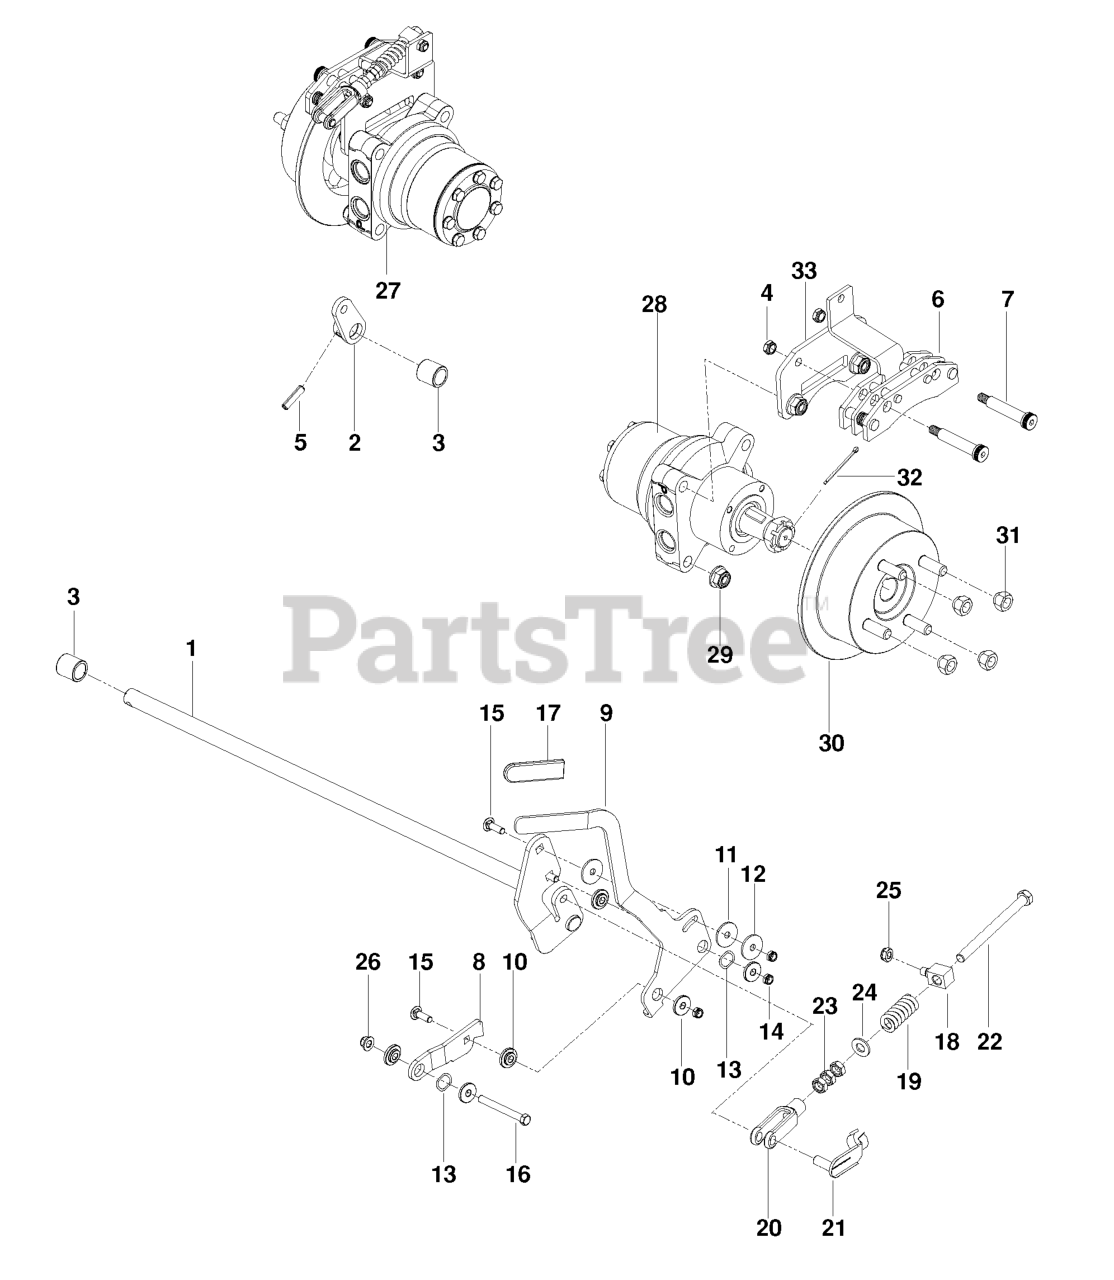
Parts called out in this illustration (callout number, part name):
1	SHAFT, BRAKE WLDMT
2	ARM, RT BRAKE
3	BUSHING, SLEEVE 3/4 X 1.0
4	NUT HEX 3/8-16 NYLON, THIN
5	5/16 DIA ROLL PIN
7	BOLT, SHOULDER, 1/2 X 2.25
8	LINK, FOLLOWER
9	LEVER.BRAKE.BLACK
10	BUSHING, BRAKE
11	WASHER, FRICTION, 1/8
12	CONE WASHER
13	WASHER, .825 X 1.087, WAVE
14	NUT HEX 3/8-16 NYLON, THIN
15	RHSNB 3/8-16 X 1-1/4
16	HCS 3/8-16 X 3-1/4 GR5 ZD
18	SWIVEL, BRAKE
20	YOKE-3/8-24 PLTD
21	PIN, CLEVIS SPRING, 3/8
22	HCS 3/8F X SPECIAL
23	NUT 3/8-24 JAM
24	WASHER 3/8 SAE FLAT
25	5/16-18 THIN PROF NY
26	NUT 3/8-16 HEX FLG NYLOC ZD
27	MOTOR, TL0310, RT
28	MOTOR, TL0310, LT
29	NUT, 1/2-13 HEX FLG NYLOC ZD
30	HUB, DISC BRAKE, W/STUDS
31	LUG NUT 1/2F
32	COTTER PIN 1/8 X 2
33	PLATE, CALIPER
